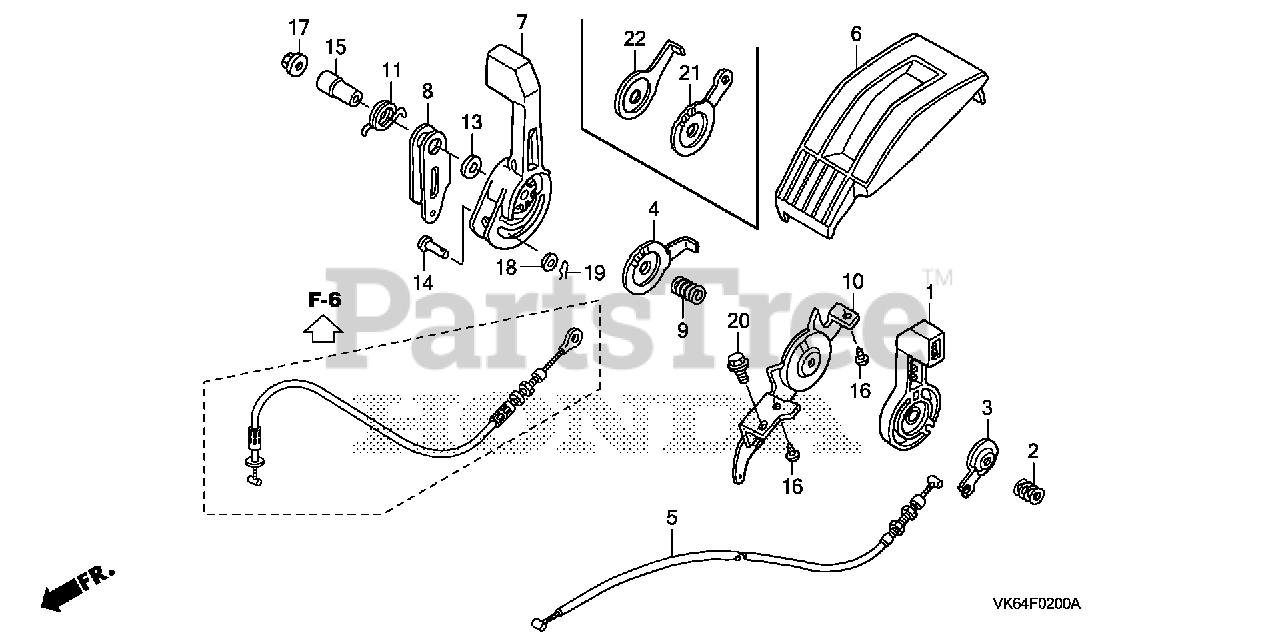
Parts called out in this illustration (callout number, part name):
1	LEVER, THROTTLE
2	SPRING, THROTTLE LEVER
3	SEAT, SPRING
5	CABLE, THROTTLE
6	COVER, CONTROL
7	LEVER, CHANGE
8	ARM, CHANGE LEVER
9	SPRING, CHANGE LEVER
10	STOPPER, LEVER
11	SPRING, ARM RETURN
14	PIN (6X22)
15	COLLAR, CHANGE LEVER
16	SCREW, TAPPING (5X12)
17	NUT, FLANGE (6MM)
18	WASHER, PLAIN (6MM)
19	PIN, LOCK (6MM)
20	BOLT, FLANGE (6X10)
21	SEAT, SPRING
22	PLATE, THRUST
